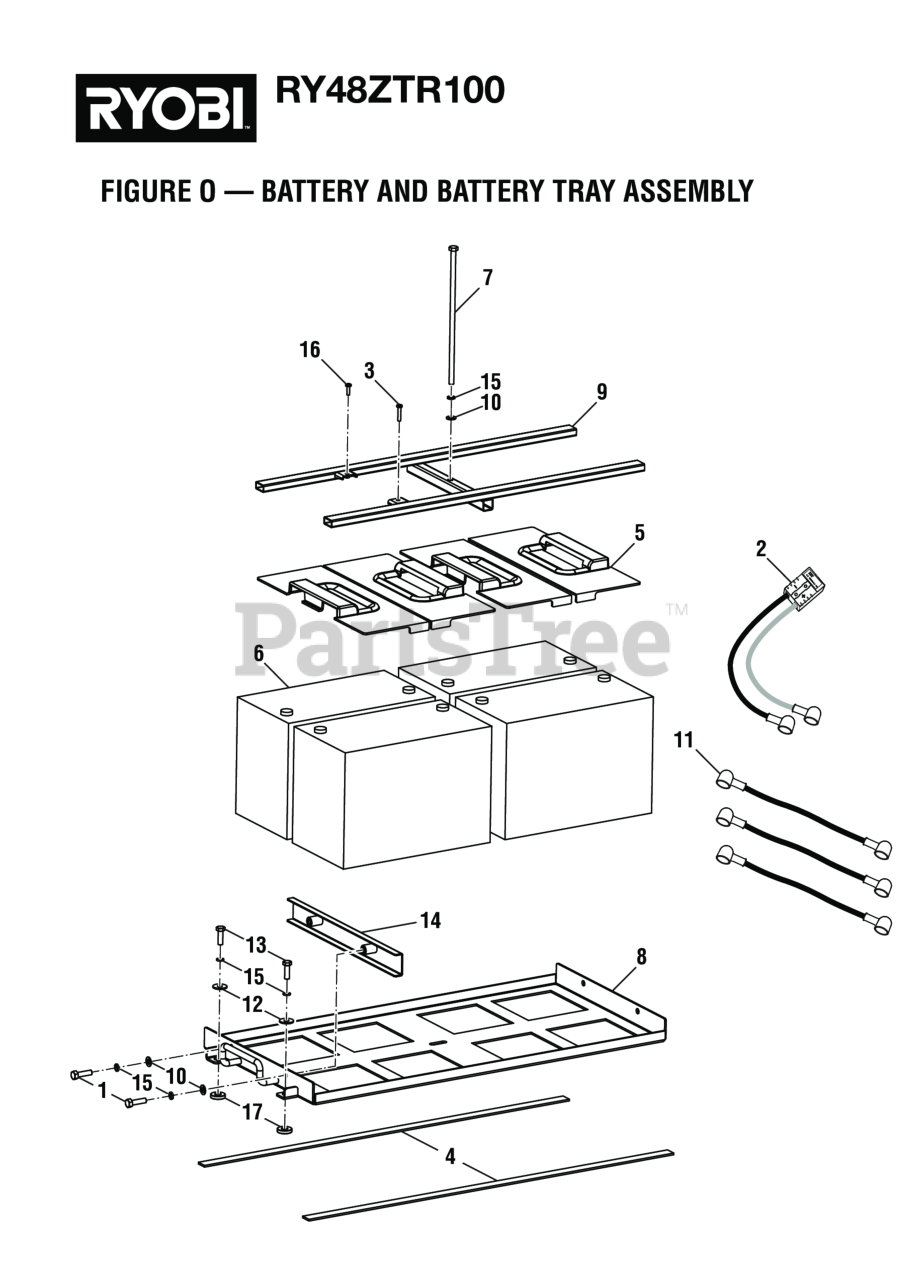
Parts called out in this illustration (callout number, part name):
1	Bolt (M8 x 25 mm)
2	Battery Cable 2, ZTR
3	Screw (M5 x 25 mm)
4	Battery Tray Slider
5	Battery Shield, ZTR
6	Battery (LPC12-100, RY48111)
7	Hex Bolt (M8 x 240 mm)
8	Battery Tray
9	Battery Tie Down
10	Washer (OD16 x ID8.4 x 1.6t)
11	Battery Cable w/Covers (Red and Black, 120 mm)
12	Washer (OD 24 x ID8.4 x 2t)
13	Bolt (M8 x 25 mm, Hex Hd.)
14	Battery Holder Bracket
15	Lock Washer (OD9.8 x ID8.5 x 5t)
16	SCREW,PPHMS, M5 X 0.8 X 16 - STEEL,
17	Metal Bushing
